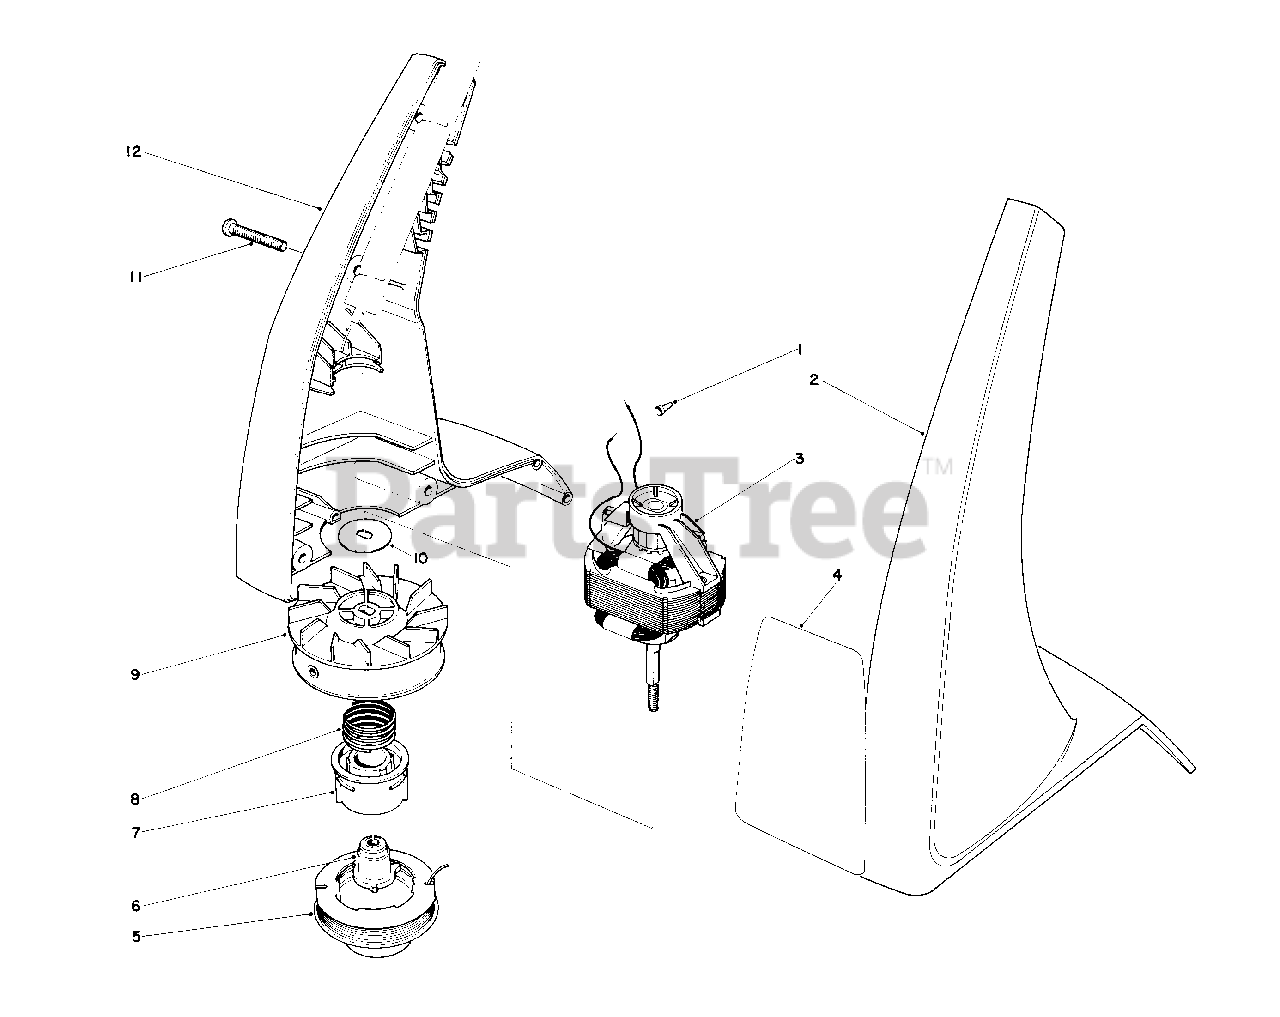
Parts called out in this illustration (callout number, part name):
1	Wire Connector
2	Left Hand Housing
5	Prewound Spool
7	Spool Core
8	Spring
9	Drum with Eyelet
10	Washer-Motor
11	Screw
12	Right Hand Housing Assembly
